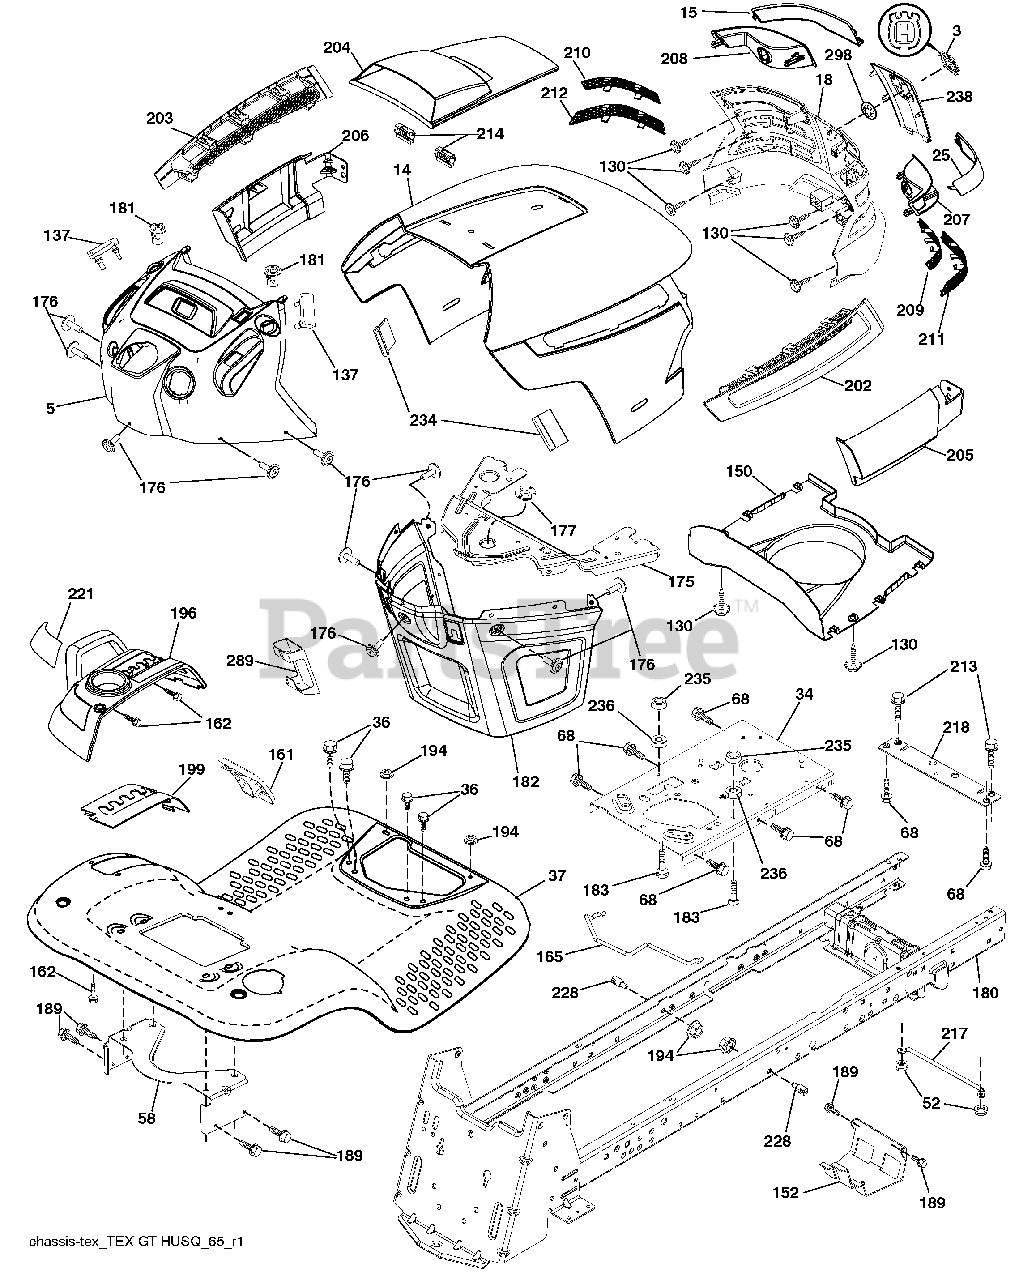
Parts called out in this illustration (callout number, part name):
3	Logo
14	Hood Asm.
18	Grille Asm.
34	Plate Engine
36	Screw 5/16-18 x 3/4
37	Fender
52	Nut Crown Lock 5/16-18
58	Bracket Fender
68	Screw 5/16-18 x 1/2
130	Screw #10 x .750 BOS Thread
137	Bumper Dash
150	Duct Heat Hood
152	Shield Browning/Debris
161	Console Fuel Window
162	Screw Hex Wsh Hi-Lo 1/4 x 1/2
165	Bracket Support Tank
175	Crossmember
176	Screw 10-24 x 5/8
177	Bushing Steering
180	Chassis
181	Bushing Mtg. Fender Crgo.
182	Dash Lower
183	Bolt Fin Hex 5/16-18 unc x 1-1/4
189	Screw 5/16-18 x 3/4
194	Nut Lock Hex Flange 5/16-18
196	Console Asm. Deck Lift
199	Plate Deck Lift
202	Vent Side Hood RH
203	Vent Side Hood LH
204	Vent Asm Hood Top
205	Skirt Hood Side RH
206	Skirt Hood Side LH
209	Insert Hex Top RH
210	Insert Hex Top LH
211	Insert Hex Bottom RH
212	Insert Hex Bottom LH
213	Bolt Hex Hd 5/16-18 unc x 3/4
214	Clip Retainer
221	Reflector LH
228	Stud Fastener
234	Bumper Hood
235	Spacer Fender
236	Nut Center Lock 5/16-18 unc
289	Plug Cruise/Phone
